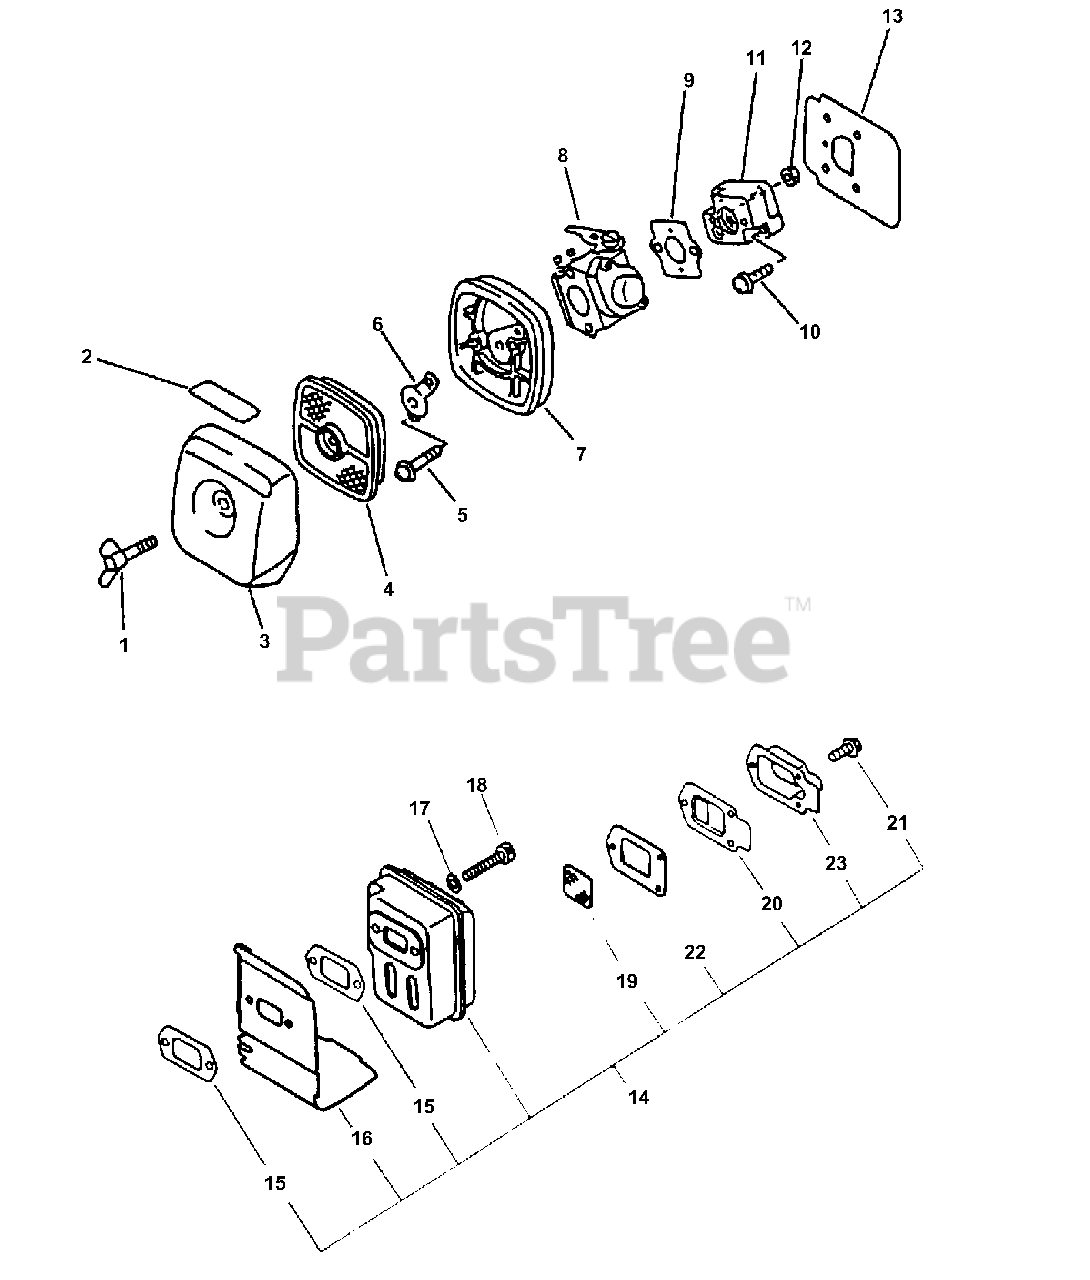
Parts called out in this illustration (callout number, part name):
1	THUMBSCREW
2	LABEL - CHOKE
3	COVER, AIR FILTER - GRAY
4	FILTER, AIR - SINGLE LAYER
5	SCREW - 5X65
6	PLATE, PREVENT
7	AIR FILTER CASE ASSY
8	CARBURETOR C1U-K47
8	CARBURETOR C1U-K52
9	GASKET, INTAKE
10	SCREW - 5X20
11	INSULATOR, INTAKE
13	SHIELD, INTAKE
14	MUFFLER ASSY
15	GASKET, EXHAUST
16	COVER, EXHAUST
17	WASHER - 5
18	SCREW - 5X55
19	SCREEN, SPARK ARRESTOR
20	GASKET, EXHAUST - INNER
21	SCREW - 4X10
22	GASKET, EXHAUST
23	GUIDE, EXHAUST - OUTER
